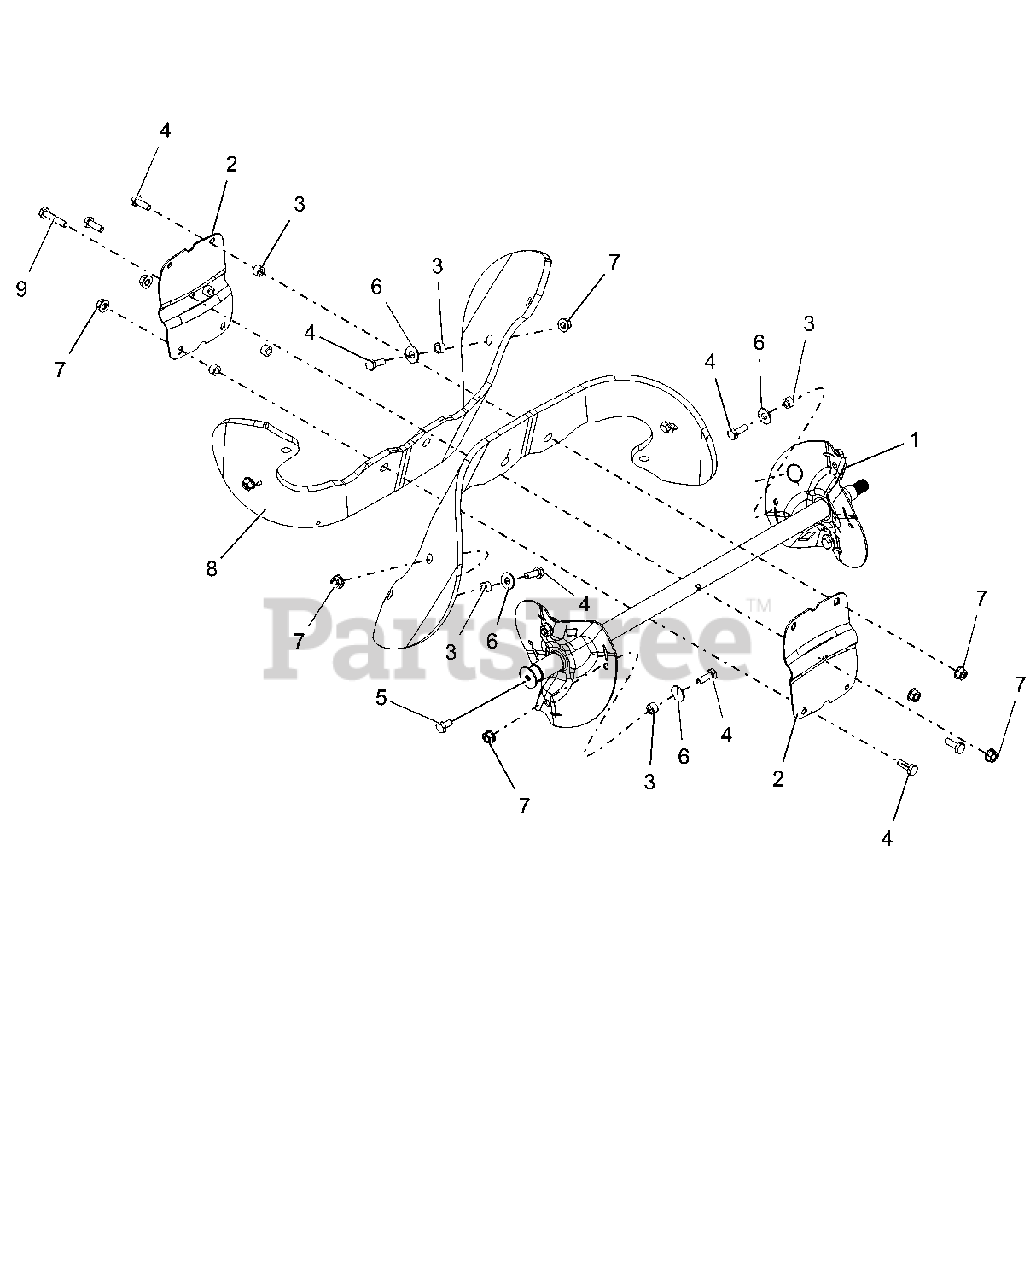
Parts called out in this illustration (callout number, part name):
1	ASSEMBLY, AUGER FRAME
2	PLATE, CENTER AUGER
3	BUSHING, .26 ID X .44 OD X .26
4	@BLT-HEX .25-20X.75 GR5 YWZC
5	@BLT-HEX .25-20X.50 GR5 YWZC
6	@WSHR-FL-STL.312X.734X.065 YWZ
7	@NUT-LK-TOP-FLG .25-20 YWZC
8	KIT, PADDLE REPLACEMENT
9	@BLT-HEX .25-20X1.25 GR5 YWZC
